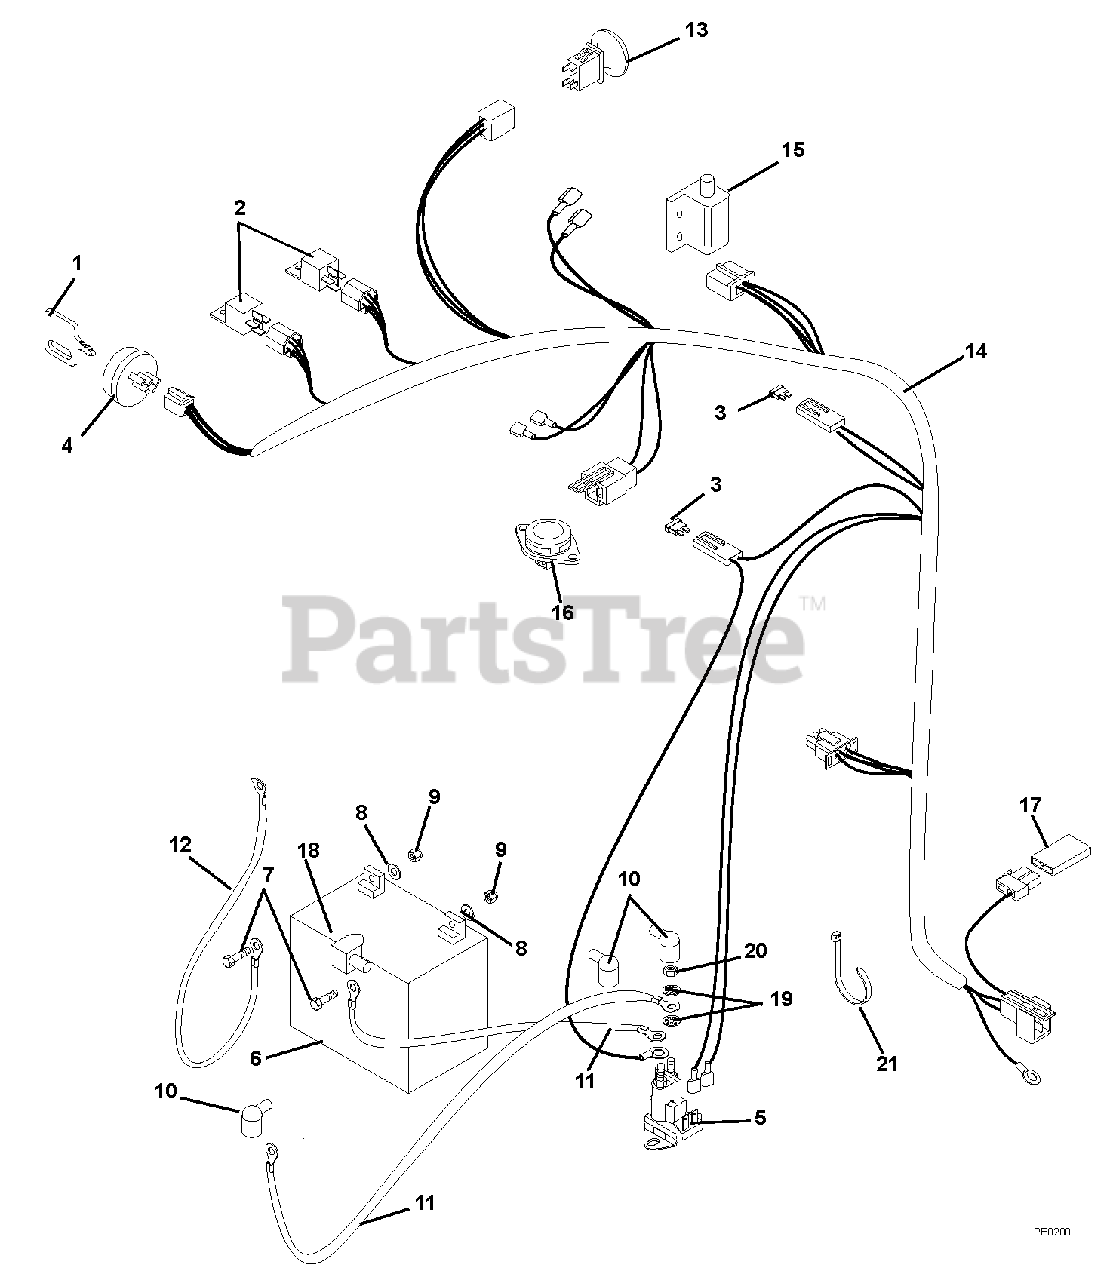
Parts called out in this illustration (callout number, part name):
1	Key with Cap
2	Relay
3	Fuse, 30 AMP
4	Key Switch
5	Solenoid
6	Battery, Exide Sealed Maintenance Free U1-250 (Purchase replacement locally)
7	Bolt, Hex .25-20 x .75 Grade 5
8	Washer, Flat Steel .281 x .62 x .065
9	Nut, KEPS .250-20
10	Boot, Eyelet Terminal
11	Starter Cable 13"
12	Ground Cable
13	Switch, Clutch With Retainer
14	Harness, Mini-Zoom/Zoom
15	Switch, Double Pole N.O. / N.O.
16	Switch, Snap Mounting (N.O.)
17	Diode, Connector Shell
18	Insulator
19	Washer, Locking .31
20	Nut, Jam .31-24
21	Cable Tie
